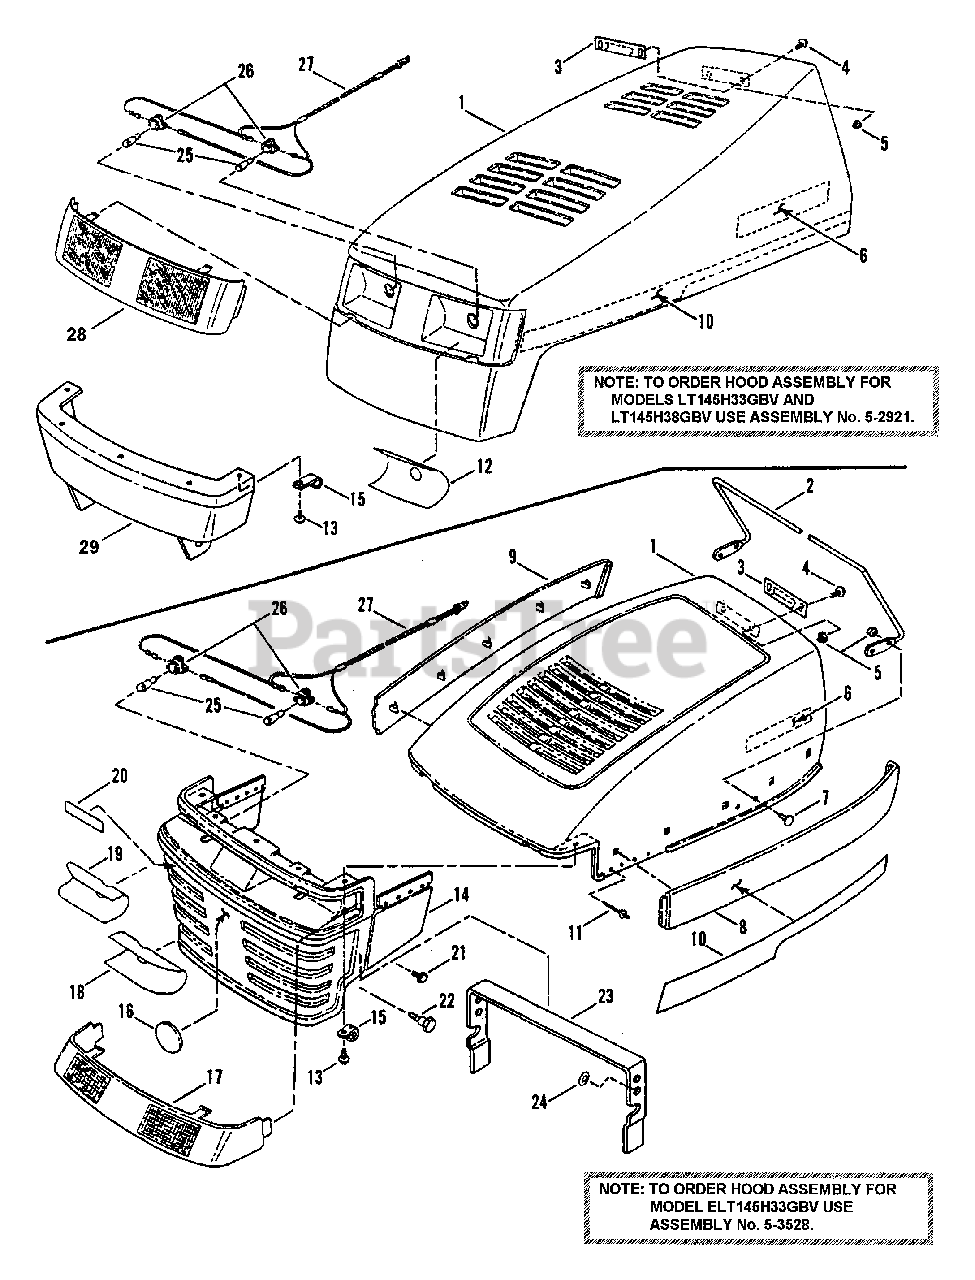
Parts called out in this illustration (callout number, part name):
1	HOOD
1	HOOD, Mozart
2	ROD, Hood Support
3	LATCH, Spring
4	SCREW, 1/4-20 x 5/8" Truss Head, Torx
5	NUT, 1/4-20 Hex Nyloc
6	DECAL - SNAPPER, 8" Molded Logo, Silver Letters
7	BOLT, 1/4-20 x 5/8" Flat Head Carriage, Grade 5
8	PANEL, Hood (Left Hand) (Black)
9	PANEL, Hood (Right Hand) (Black)
10	DECAL, Hood (Right Hand)
10	DECAL, Hood (Left Hand)
11	RIVET, 1/8" Pop
12	DECAL, Clear Lens (Left Hand)
12	DECAL, Clear Lens (Right Hand)
13	SCREW, M4.8 x 1.59 x 16.00MM, Special
14	GRILLE, Hood
15	CLIP, "J"
16	DECAL, Molded Medallion
17	LENS, Grille (Headlights)
18	DECAL, Reflect (Left Hand)
19	DECAL, Reflect (Right Hand)
20	DECAL - SNAPPER, 4" Molded Logo (Silver Letters - Blue Stripe)
21	SCREW, 5/16-18 x 1/2" Self-Tapping, Grade 5
22	BOLT, Shoulder, 3/8-16 x 1-1/4" Hex Socket, Torx
23	BRACE, Hood Support
24	RETAINER, 5/16" Bolt
25	BULB, Headlights
26	SOCKET, Headlight Bulb
27	HARNESS, Headlight Wiring
28	LENS, Clear
29	BUMPER, Front Hood Support
